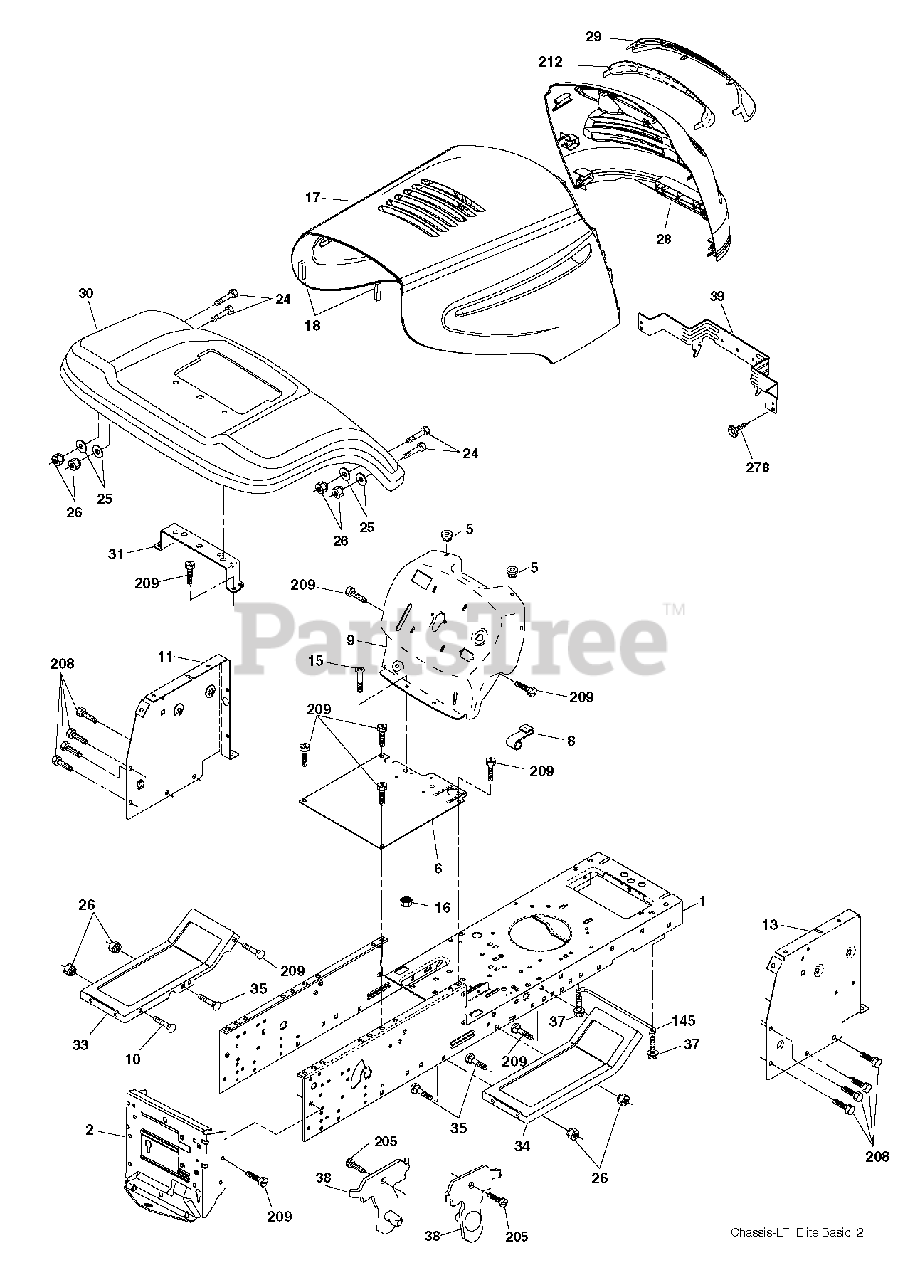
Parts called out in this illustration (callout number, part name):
1	CHASSIS
2	DRAWBAR, 12GA
5	BUMPER.RUBBER.HOOD
8	CLIP RETAINER
9	FENDER LT SH
10	BOLT D
11	PANEL.DASH.LH.LTX
13	PANEL.WELDMENT.DASH.R
16	NUT
17	GRILLE.BASIC.NO LIGHTS (NLARS)
18	BUMPER.HOOD.LARGE.1.75"
25	WASHER
26	NUT
29	LENS.GRILLE.BASIC.BAR.LT.CLR
30	CONSOLE.SVC.SHIFT.LTST.5SP
31	BRACKET FENDER
33	FOOTREST.PNT.RH
38	BRACKET.ASM.PIVOT.MOWER.REAR
39	BRACKET PIVOT
145	ROD.PIVOT.HOOD
208	SCREW 3/8-16X1/2
209	SCREW, 3/8-16X3/4
212	INSERT LENS REFLECTIVE
278	SCREW.#10 X 0.750.BOS THREAD
